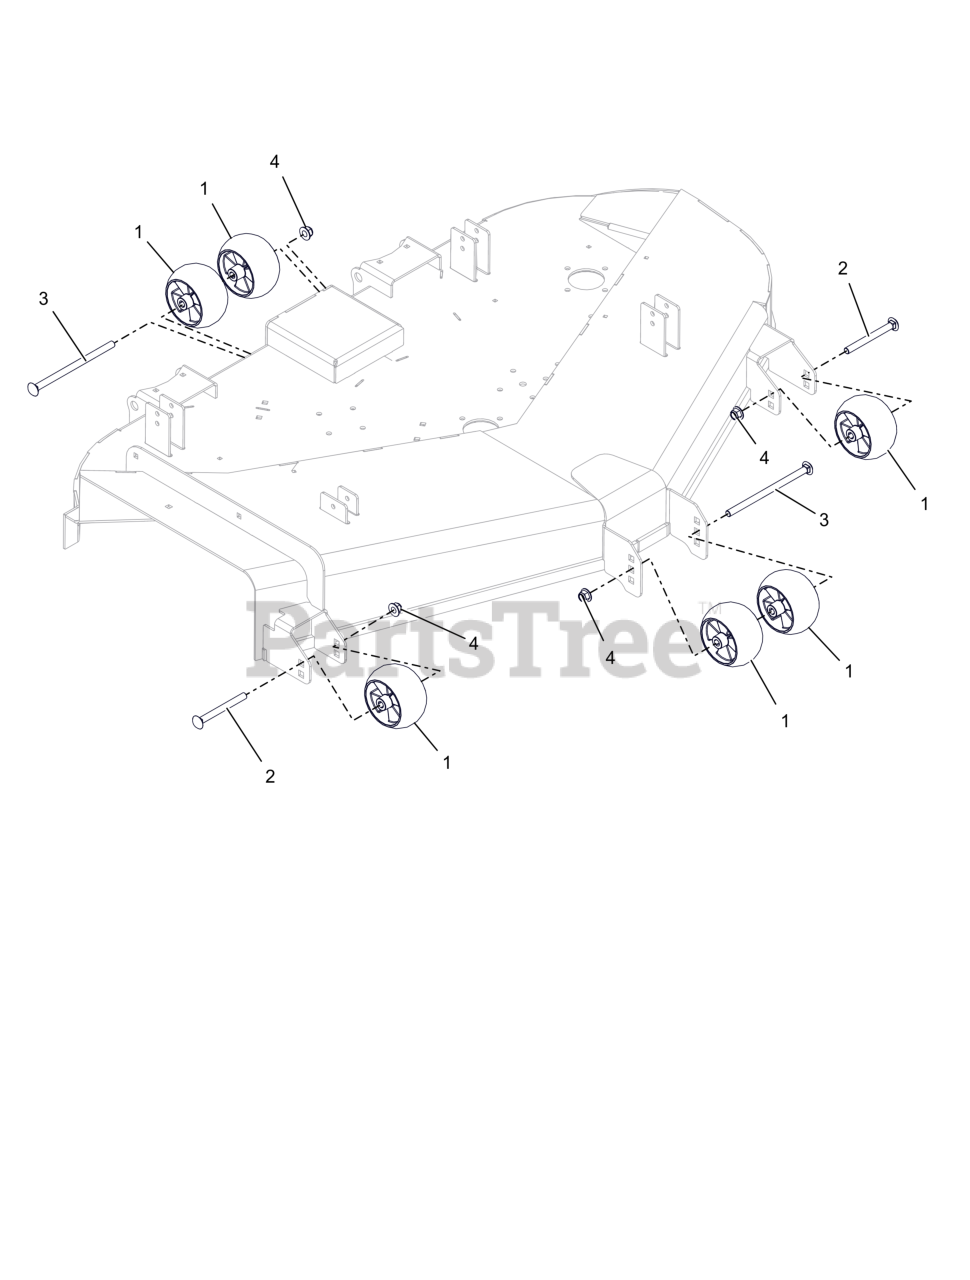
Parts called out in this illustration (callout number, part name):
1	WHEEL, ANTI SCALP - 5X3 CTR W/RIBS
2	BLT, RHSN .50-13X5.00 G5 ZCC
3	BTL,RHSN .500-13 X 8.5S G5 ZCC
4	NUT,NYL-FLG .50-13 GF ZCC
